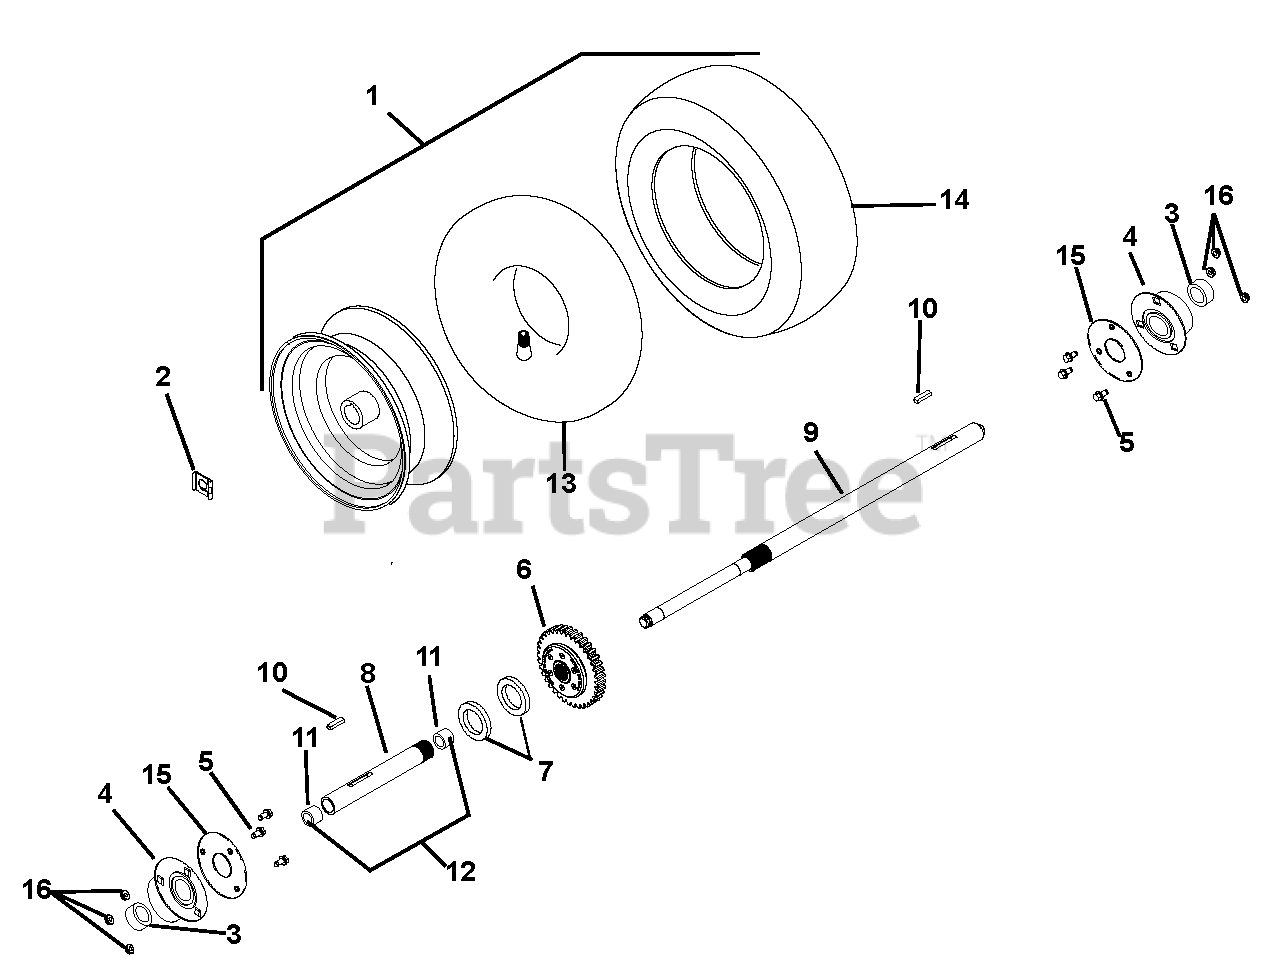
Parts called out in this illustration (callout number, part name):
1	Tire/Wheel Assembly RH 16 x 6.50 - 8 Differential (Includes 14-15)
2	Clip, Snap
3	Spacer, Pro Axle Bearing
4	Bearing-Flange, 1.003/1.000 3 Bolt
5	Bolt-Hex .25-20 x .75
6	Differential, Hilliard
7	Washer, Flat Nylon 1.062 x 2.00 x .134
8	Axle, Differential-Short
9	Axle, Differential-Long
10	Key .25 x .188 x 1.00
11	Bushing, Sleeve .706 x .764 x .75
12	Axle, Differential with Bushings (Includes 8 and 12)
13	Tube 16 x 6.50- 8
14	Tire, X-TRAC 16 x 6.5-8
15	Plate, Bearing Spacer
16	Top Flange Locking Nut .25-20
